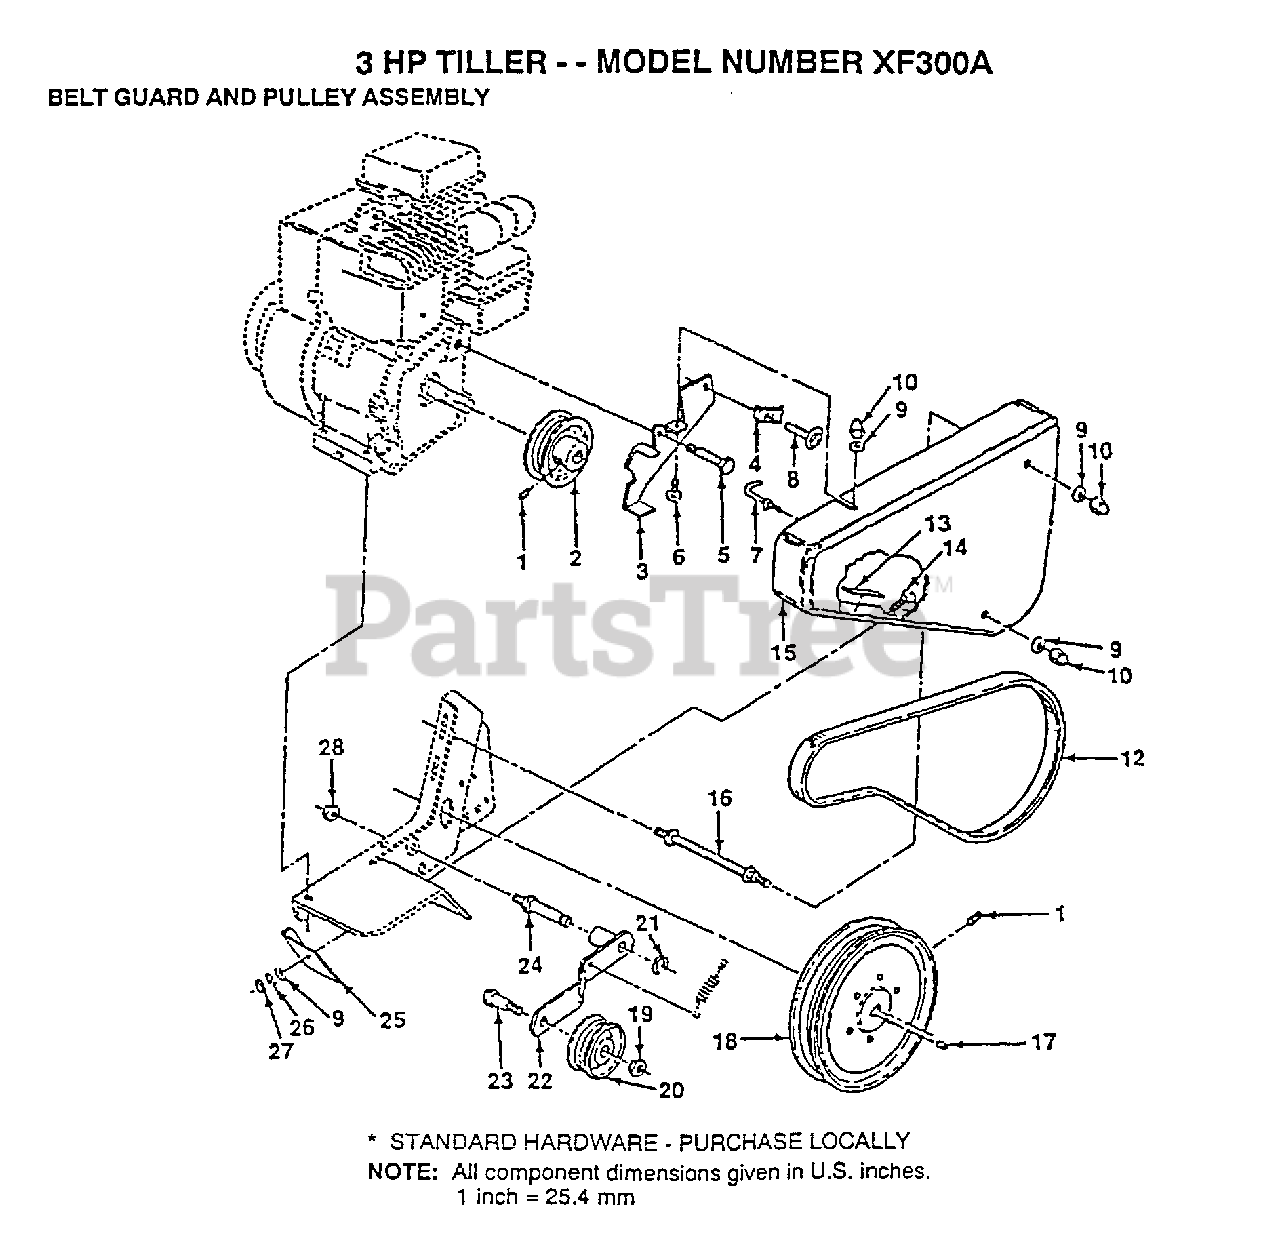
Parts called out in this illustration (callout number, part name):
1	SET SCREW
4	CONDIUT CLIP T
6	BOLT
9	WASHER
10	NUT-CAP TI
13	PAD IDLER TI
14	BOLT T
16	BOLT TI
17	KEY T
18	TRANS SHEAVE RT
19	NUT
21	KLIP RING TI
22	IDLER ARM TI
24	SHAFT IDLER TI
25	SHIELD-DIRT TI
26	LOCKWASHER
28	JAM NUT TI
